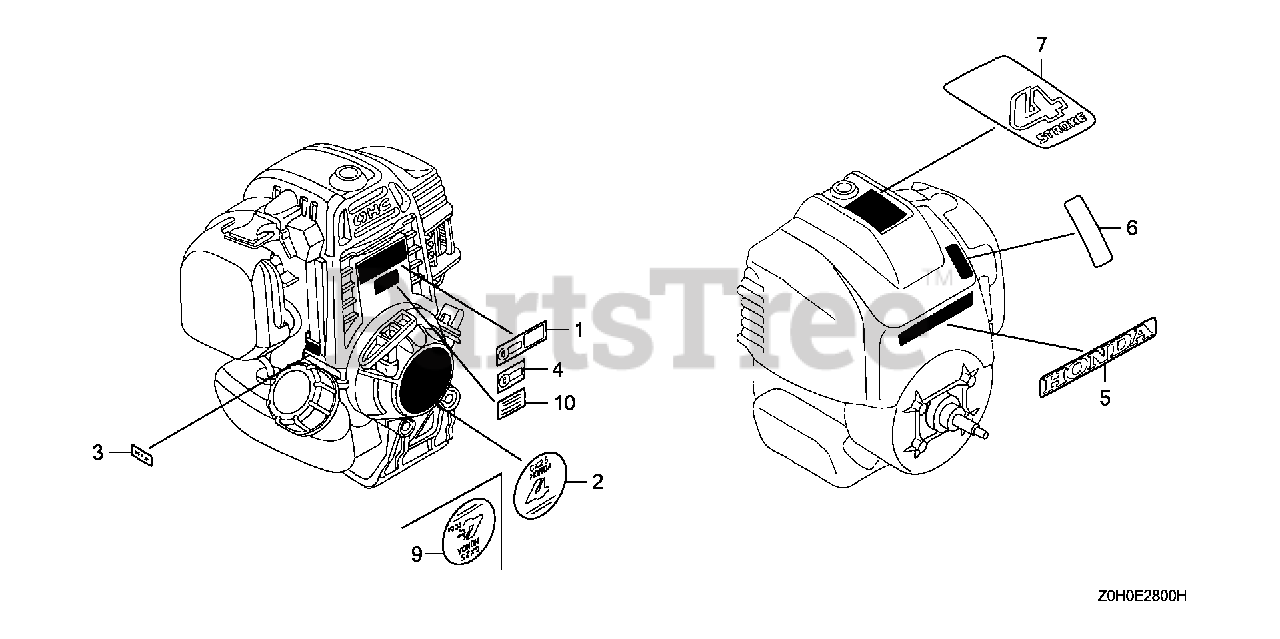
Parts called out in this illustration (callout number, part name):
2	MARK, EMBLEM
3	MARK, TYPE (SA2)
5	MARK, HONDA
7	MARK (4-STROKE)
